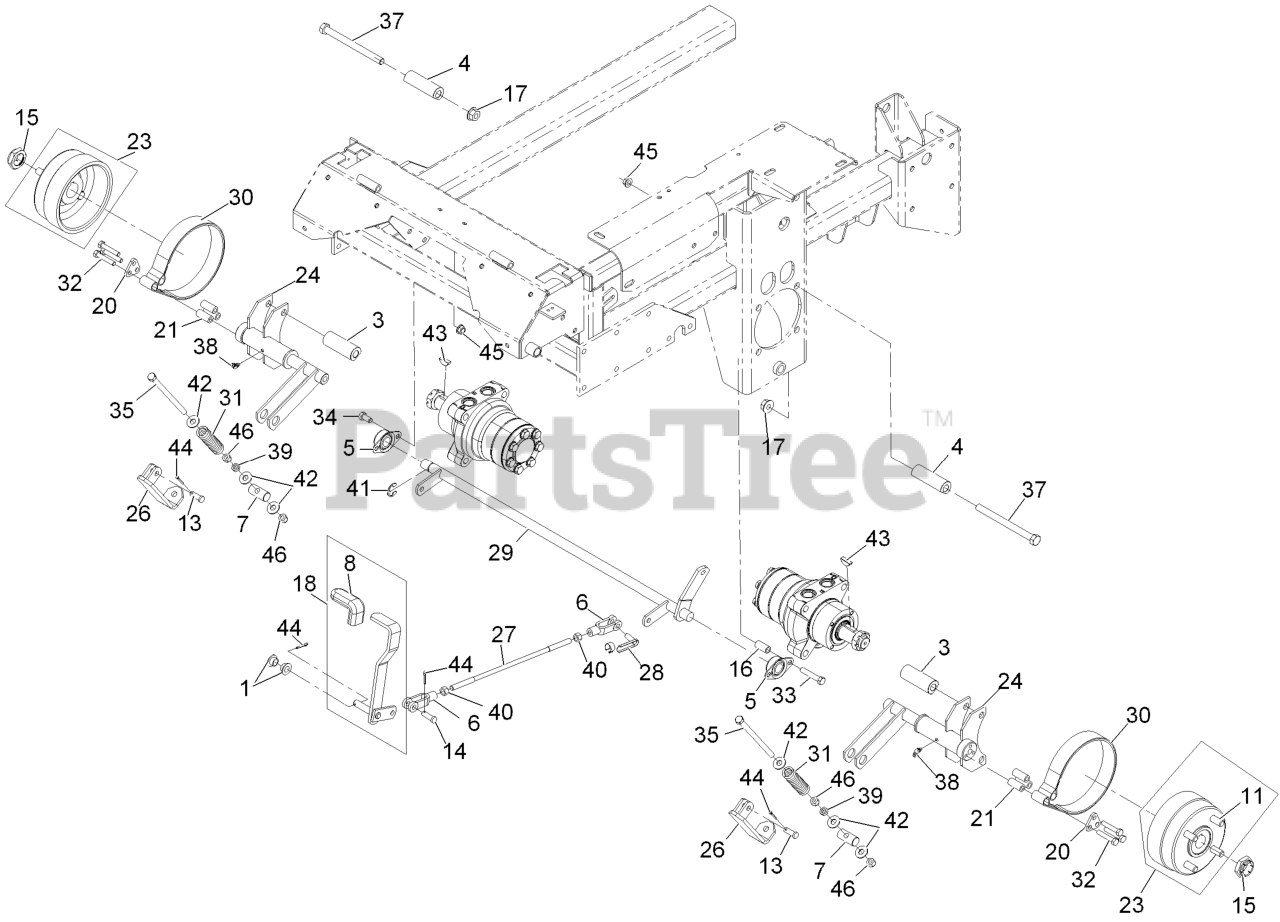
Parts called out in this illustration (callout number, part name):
1	BEARING-CONTROL
3	SPACER-WHEEL, SHORT
4	SPACER-WHEEL, LONG
5	BEARING-FLANGE, SIDE
6	YOKE-LINKAGE, BRAKE
7	PIN-TRUNION
8	GRIP-LEVER
11	STUD-WHEEL
13	PIN-CLEVIS
14	PIN-CLEVIS
15	LOCKNUT
16	SPACER-RETAINER, BRAKE
17	NUT-HHF
18	BRAKE LEVER AND GRIP ASM
20	RETAINER-BAND, BRAKE
23	HUB W/STUDS ASM
24	BRAKE-WIDE
26	LINKAGE-BRAKE, LOWER
27	ROD-BRAKE
28	PIN-SPRING, CLEVIS
29	SHAFT-BRAKE
30	BAND,BRAKE
31	SPRING-COMPRESSION
32	SCREW-HH
33	SCREW-HH
34	SCREW-HH
35	BOLT-TAP, HH
37	SCREW-HH
38	FITTING-GREASE
39	NUT-JAM
40	NUT-HEX
42	WASHER-FLAT
43	KEY-WOODRUFF
44	PIN-COTTER
45	NUT-HHF, WHIZ
46	NUT-LOCK, NI
